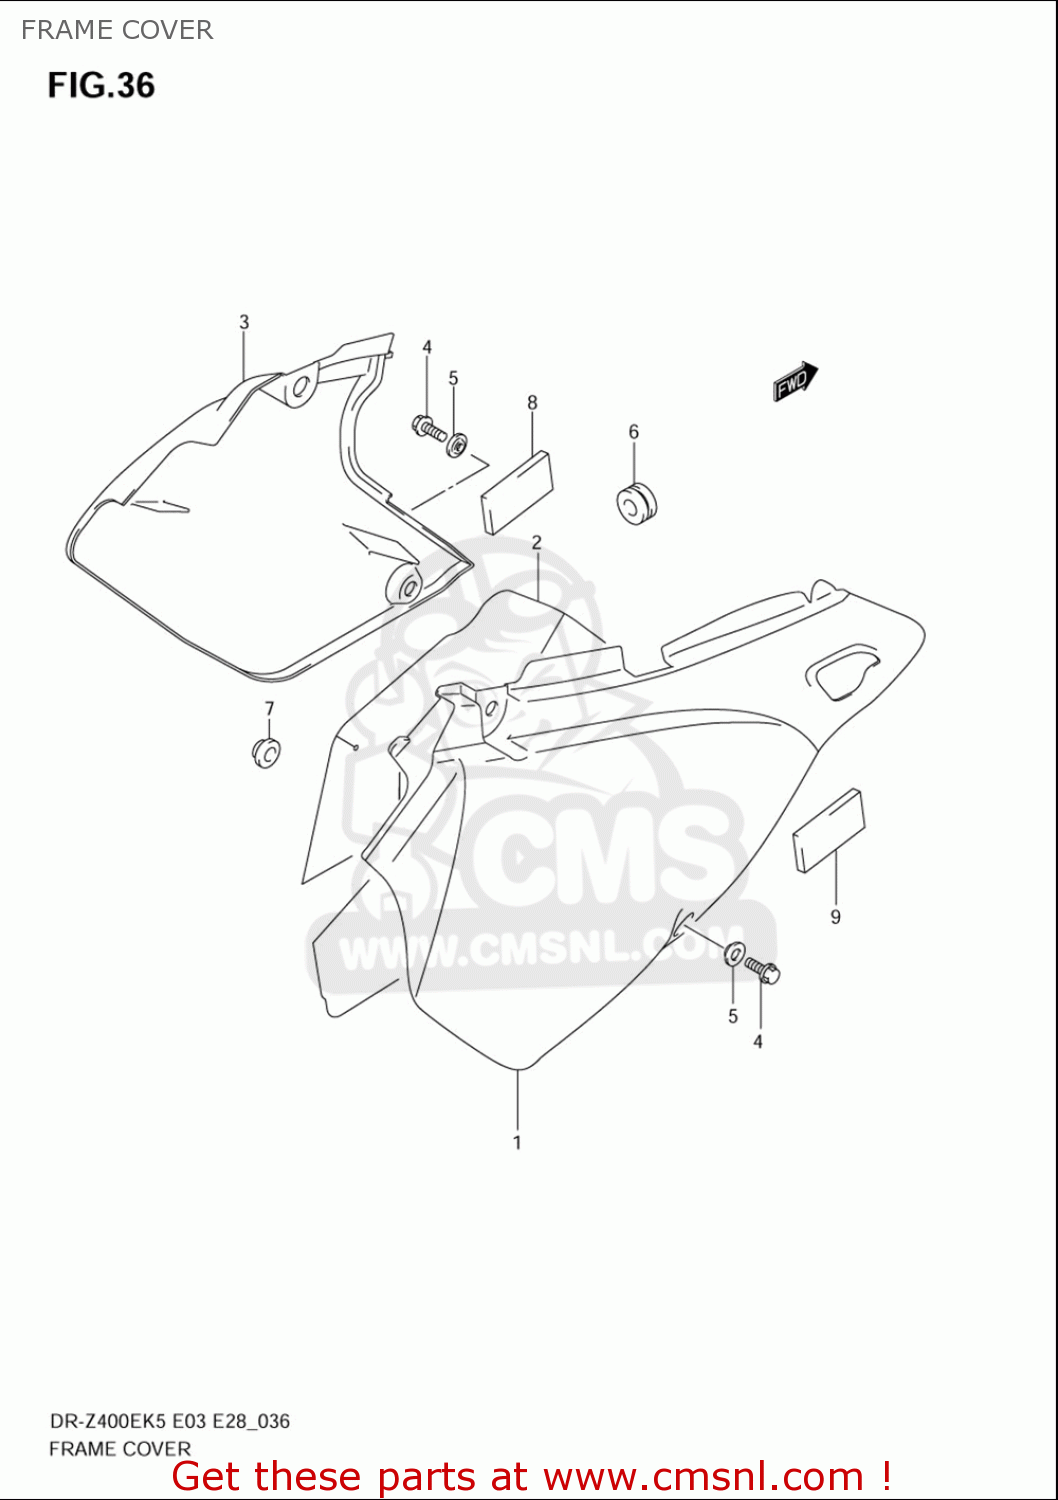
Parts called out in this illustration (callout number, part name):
1	COVER,FRAME,RIGHT
2	SHIELD,FRAME COVER,R
3	COVER,FRAME,LEFT
4	BOLT
5	WASHER
6	CUSHION
7	CUSHION
8	CUSHION,FRAME COVER,L
9	CUSHION
